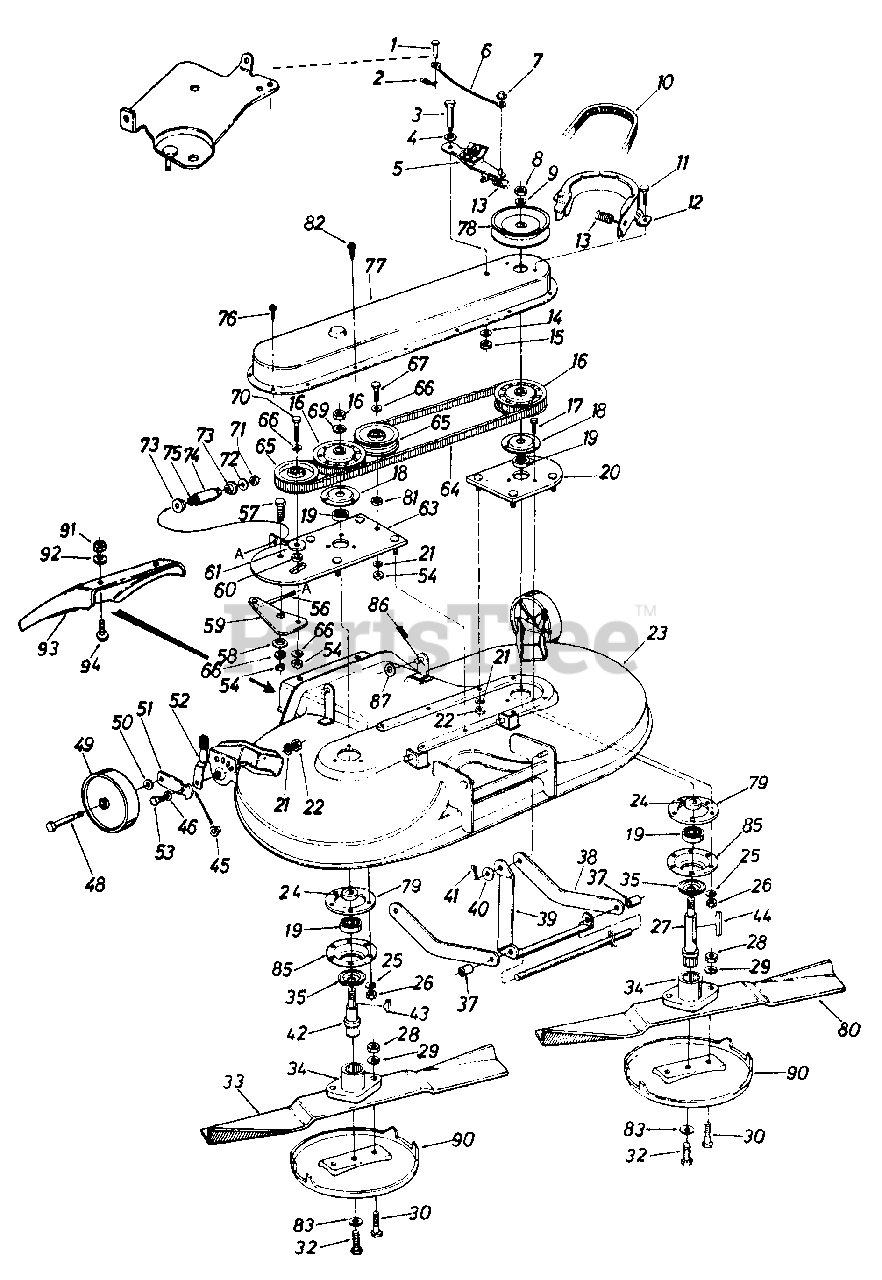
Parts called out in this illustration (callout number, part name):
1	Clevis Pin 1/4" Dia. x 1/2" Lg.
2	Hairpin Cotter 1/4" Dia.
3	Shld. Bolt .437" Dia. x.180" Lg. (5/16-18)
4	Wave Washer 7/16" Scr.
5	Spindle Brake Arm Ass'y.
6	Brake Cable Ass'y.
7	Push Cap 1/4" Stud
8	Hex Jam Nut 5/8-18 Thd.
9	Bell.-Wash. 5/8" I.D. x 1.25" O.D.
10	"V"Belt
11	Hex Wash. Hd. Self Tap Scr. 1/4-20 x .50" Lg.
14	Bell.-Wash. .340" I.D.
15	Hex Cent. L-Nut 5/16-18 Thd.
16	Sprocket Pulley Ass'y.
17	Hex Bolt 5/16-24 x 1.00" 4. (Grade 5)
18	Bearing Housing
19	Ball Bearing .787" I.D. x 1.85" O.D.
20	Spindle Plate Ass'y.
21	L.-Wash. 3/8" I.D.*
22	Hex Jam Nut 3/8-24 Thd.
23	44" R.D. Deck Ass'y.
24	Spacer
25	L.-Wash. 5/16" I.D.*
26	Hex Nut 5/16-24 Thd.*
27	Blade Spindle - L.H.
28	Hex Nut 5/16-24 Thd.*
29	L.-Wash. 5/16" I.D.*
30	Hex Bolt 5/16-24 x 1.00" Lg.
32	Hex Bolt Cent. L.-3/8 x 24 x 88" Lg.
33	22.5" Blade-L.H. Rotation
34	Blade Adapter
35	Bearing Shield
37	Spacer 5/8" I.D. x 7/8" O.D.
41	Cotter Pin 3/32" Dia. x 1.00" Lg.*
42	Blade Spindle - R.H.
43	Sq. Key 3/16" x .75" Lq.*
44	Sq. Key 3/16" x 1.50" Lg.*
45	Shoulder Spacer
46	Bell.-Wash. .400" I.D.
48	Shld, Bolt 3/8-16 x 1.41" Lg.
49	Wheel Ass'y. Comp. 6"x 1.38
50	Bell-Wash. 3/8" I.D.
51	Wheel Pivot Bar
52	Spring Lever Ass'y. w/knob
53	Hex Bolt 3/8-24 x 1.25" Lg. (Grade 5)
54	Hex Cent. L-Nut 3/8-24 Thd.
56	Adjustment Link 5/16-18 x 4-9/16" Lg.
57	Hex Bolt 3/8-24 x 1.00"
58	Shld. Spacer.625" I.D.
59	Belt Idler Brkt.
60	Spacer.380" I.D. x .625" O.D. x .265
61	Fl.-Wash. .38" I.D. x 1.37" O.D. x .125
63	Spindle & Idler Mount Plate Ass'y.
64	HTD Twin Power Belt
65	Fl.-Idler Pulley 3.50" O.D.
66	Bell.-Wash. .38" I.D.
67	Hex Bolt 3/8-24 x 1.75" Lg. (Grade 5)
69	Bell.-Wash. 5/8" I.D.
70	Hex Bolt 3/8-24 x 2.00" Lg.
71	Hex Insert L.-Nut 5/16-18 Thd.
72	Fl.-Wash. .344" I.D. x 1.125" O.D. x .125
73	Shld. Spacer.625" I.D.
74	Spacer-Adj. Bolt
75	Compression Spring
76	Hex Wash. Hd. Self Tap Scr. 1/4-20 x .50" Lg.
77	Belt Cover
78	Deck Drive Pulley
80	22.5" Blade- R.H. Rotation
81	Fl.-Wash. .38" I.D. x 1" O.D.
82	Hex Wash. Hd. Self Tap-Scr. 1/4-20 x .75" Lg.
83	L.-Wash.3/8"1.D. Heavy Duty
86	Hairpin Cotter
87	Fl-Wash. 1/2" I.D.
92	L.-Wash. 1/4" I.D.*
